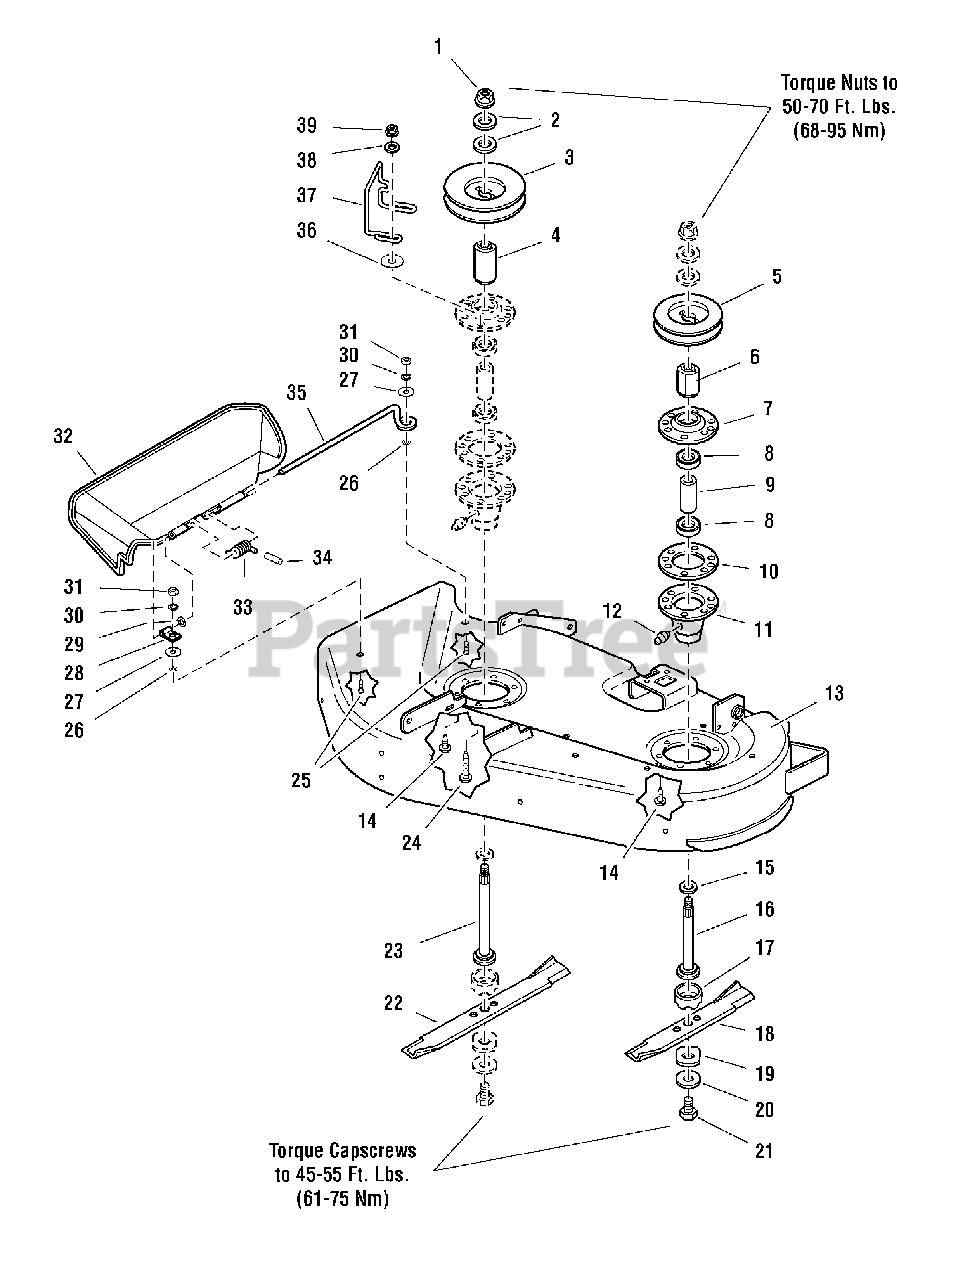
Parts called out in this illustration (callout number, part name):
1	NUT, Hex Flange, 9/16-18
2	WASHER, Bellville .56ID x 1.34 OD x .05T
7	COVER, Arbor Housing
10	GASKET, Foam
11	HOUSING ASSEMBLY, Arbor Bottom, w/Lube Fitting
12	FITTING, Lube
13	MOWER HOUSING, 34"
14	CAPSCREW, Hex Washer Head, Taptite, 5/16-18 x 3/4, Black
16	SHAFT, Arbor
17	SHIELD, Grass
18	BLADE, Mower, 14.42
19	WASHER, Hex, Special
20	WASHER, Spring
21	CAPSCREW, Hex Head, 7/16-14 x 1-1/4, Black
22	BLADE, Mower, 19.90
23	SHAFT, Arbor
24	CAPSCREW, Hex Washer Head, Taptite, 5/16-18 x 1-1/2, Black
25	CARRIAGE BOLT, 1/4-20 x 7/8, Black
26	NUT, Push, 1/4, Black
27	WASHER, 1/4, Black
28	CLAMP, Wire, 5/16 Diameter
29	WASHER, 5/16
30	LOCKWASHER, 1/4, Black
31	NUT, Hex, 1/4-20, Black
32	DEFLECTOR, Plastic
33	SPRING, Torsion
34	CAP, Spring End
35	ROD, Deflector
36	WASHER, 5/16, Black
38	WASHER, 5/16, Black
39	NUT, Hex Flange, 5/16-18
